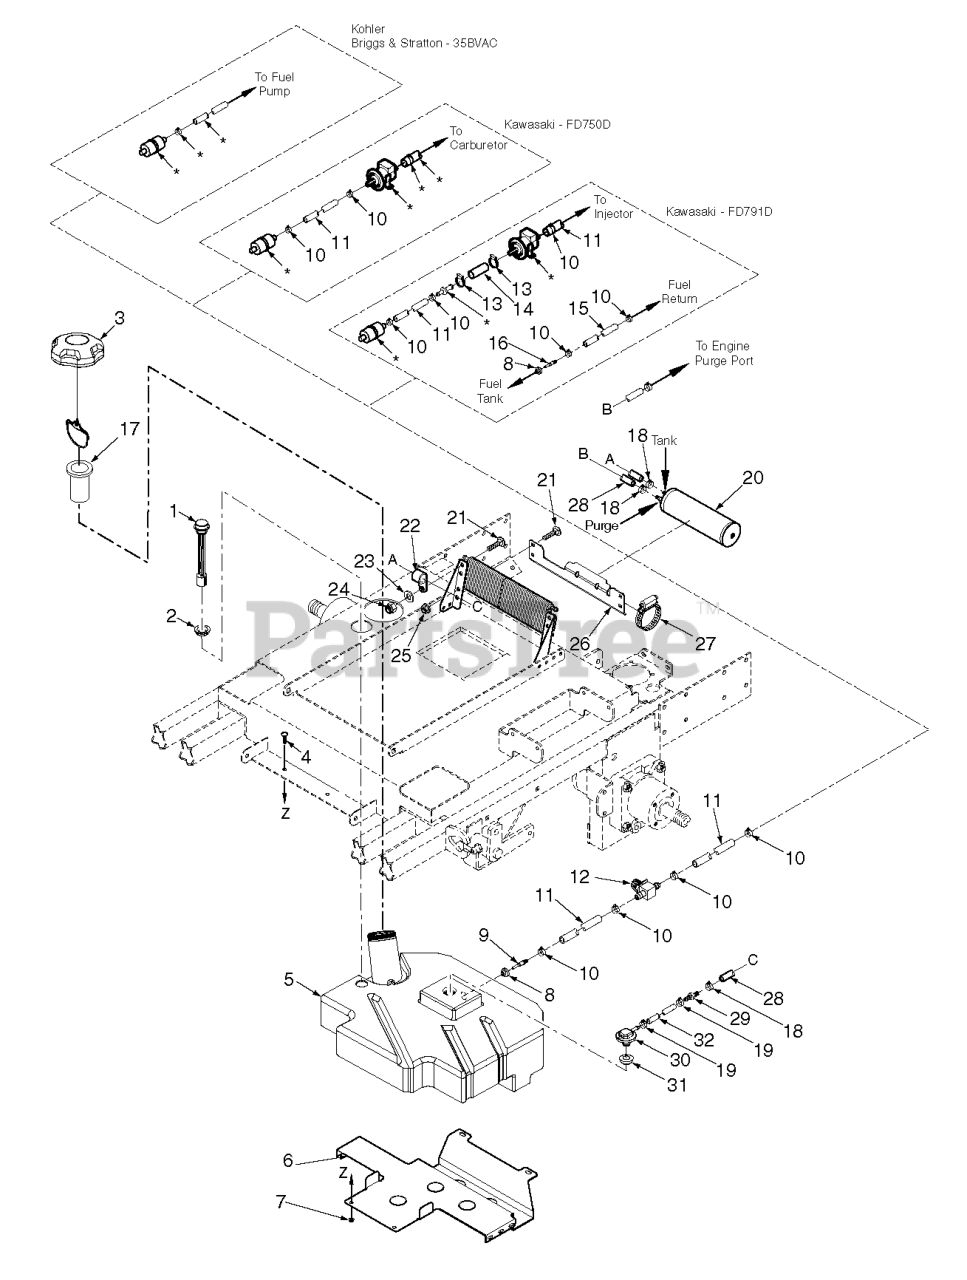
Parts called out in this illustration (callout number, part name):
1	Fuel Gauge Assembly
2	Seal, Fuel Gauge
3	Fuel Cap, Tethered
4	Bolt, Carriage 1/4-20 x 3/4"
5	Fuel Tank Assembly, Low Perm. - STT
5	Fuel Tank Assembly, Low Perm. - STT-DFI
6	Support Bracket, Fuel Tank
7	Nut, 1/4-20 Serrated Flange
8	Bushing, .56 Dia. Viton
9	Hose Fitting
10	Clamp, Fuel Hose 5/16" I.D. (791DFI)
11	Fuel Hose, 5/16" I.D. Non-Perm (791DFI) - Order by Inch
12	Valve, Fuel Shut-Off (791DFI)
13	Clamp, .87" Max. Dia
14	Fuel Hose, 1/2" I.D. Non-Perm - Order by Inch
15	Fuel Hose, 1/4" I.D. Non-Perm (791DFI Fuel Return) - Order by Inch
16	Return Fitting, Straight
17	Tube, Fuel Tank Insert - 6"
18	Clamp, Vapor Recovery Hose 3/16"
19	Clamp, Fuel Hose 7/32 ID
20	Carbon Canister
21	Bolt, Carriage 1/4-20 x 3/4"
23	Flatwasher, 1/4-.281 x .562 x .049
24	Nut, 1/4-20 Elastic Stop
25	Nut, 1/4-20 Serrated Flange
26	Bracket, RH Canister Mounting
28	Hose, 3/16 (order by inch)
29	Mender, 1/4 x 3/16 w/.02 Hole
30	Valve, Rollover
31	Grommet, Kelch Row
